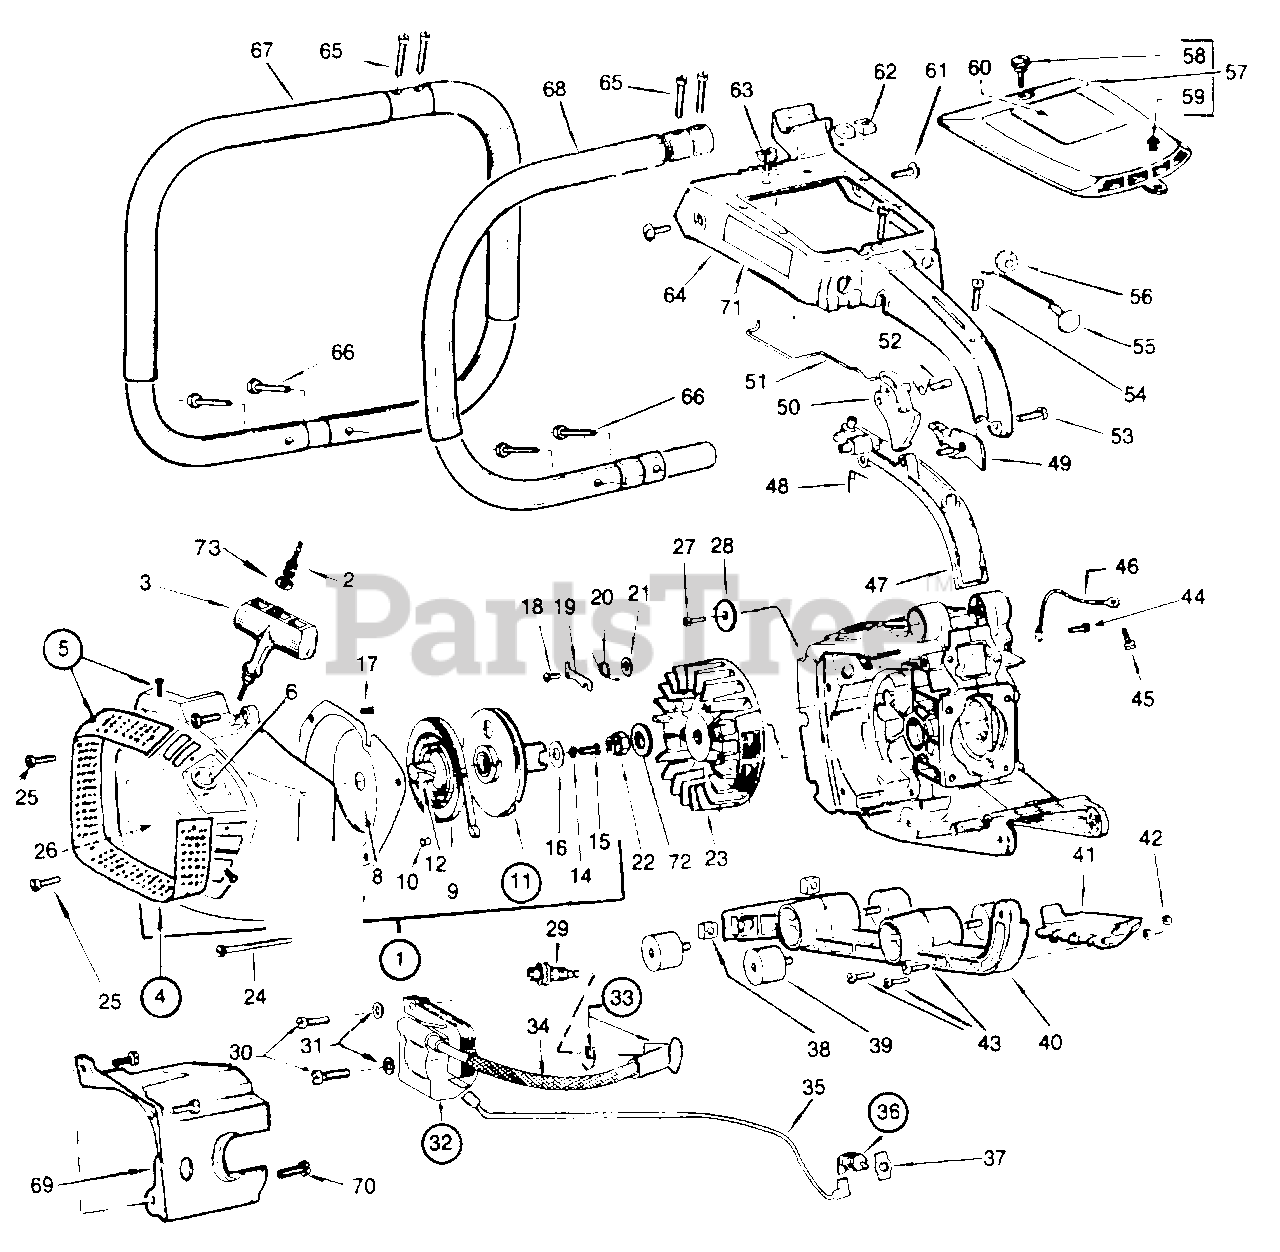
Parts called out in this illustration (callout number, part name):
1	Starter Assy Complete (Gold)
2	Starter Cord
3	Starter Handle
4	Starter Cover Assy (Gold)
5	Blower Cover Screen
9	Rewind Spring (Bridle Type)
10	Bushing - Starter Spring
11	Starter Pulley
12	Starter Bushing
14	Lockwasher
17	Screw 1/4 - 20 X 1/2.
18	Pawl Pivot
20	Pawl Spring
23	Flywheel
24	Screw - Hex Head
25	Screw - Hex Head
26	Side Decal - Poulan Pro
27	Screw - Guard/Cover
29	Spark Plug
30	Screw #8
31	Washer - #8
32	Module & Switch Wire Assy
33	Spark Plug Boot & Clip
35	Switch Wire - Module Switch
36	Grounding Switch
37	Switch Plate
39	Shock Absorber
40	Bottom Frame (Grey)
41	Rear Hand Guard (Grey)
43	Screw 8 - 32 X 1
44	Plate Screw
45	Terminal Screw
46	Ground Wire
47	Lower Grip Assy (Grey)
48	Spring - Throttle Trigger
49	Throttle Lockout Lever (Gold)
50	Throttle Trigger (Gold)
51	Throttle Link
52	Throttle Pin
54	Screw - Lwr Grip
55	Choke Knob & Wire Assy
57	Top Cover Assy (Grey)
58	Knob Cover Knob-Knurled
60	Decal - Top Cover
61	Screw - Shock Mount
64	Top Framer - Man. Oiler (Grey)
65	Screw Handle 1/4 - 28 X 1/8
67	Front Handle - Full Wrap
68	Front Handle - Half Wrap
69	Cylinder Shroud (Grey)
70	Screw 10 - 24 X 5/8
71	Decal - Top Frame
72	Washer - F/W
73	Washer - Rope
